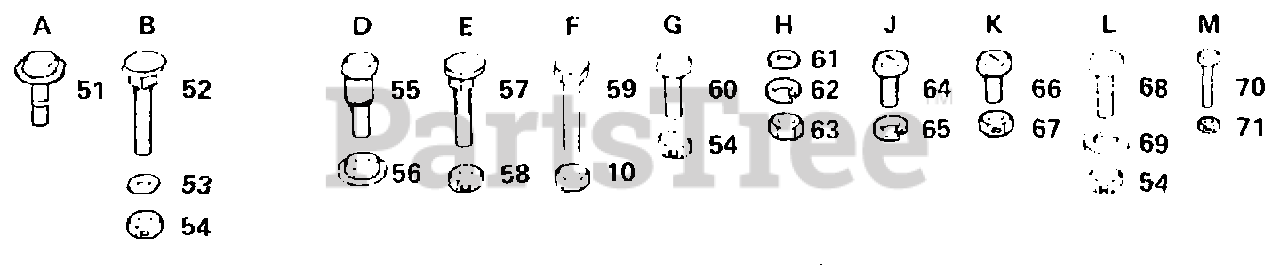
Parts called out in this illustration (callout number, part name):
51	SCREW LT
52	BOLT
53	WASHER
55	SHOULDER BOLT T
56	NUT T
57	BOLT
58	LOCKNUT
59	BOLT
61	WASHER PM
68	BOLT
69	WASHER M
70	LOCKWASHER
71	NUT T
